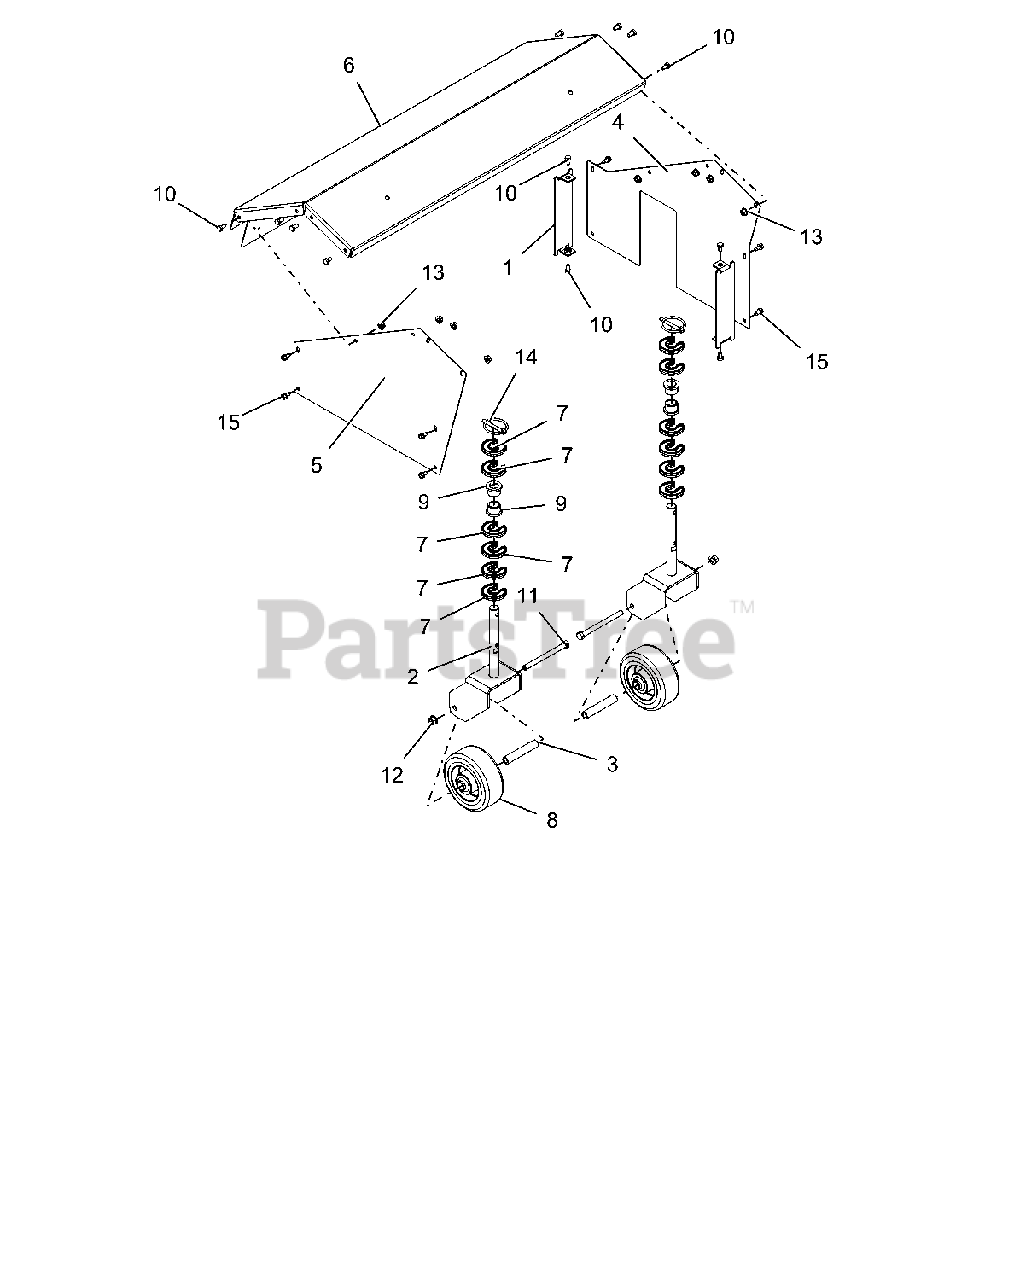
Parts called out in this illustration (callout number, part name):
1	COVER,END
2	FORK, CASTER-BRUSH
3	SPACER, CASTER WHEEL
4	COVER, LH SIDE-BRUSH
5	COVER, RH SIDE-BRUSH
6	COVER, TOP-28" BRUSH
7	CLIP-HOC FIXED
8	WHEEL, CASTER - 5"OD
9	BUSHING, FLANGE .75X.75X1.0
10	BLT-HEX .25-20X.50 GR5 YWZC
11	BLT-HEX .38-16X4.50 GR5 YWZC
12	NUT-LK-TOP-FLG .38-16 YWZC
13	NUT-LK-TOP-FLG .25-20 YWZC
14	PIN, LYNCH - .25 X 1.25
15	SCR-TAP .25-20X.50 HWH TR YWZ
